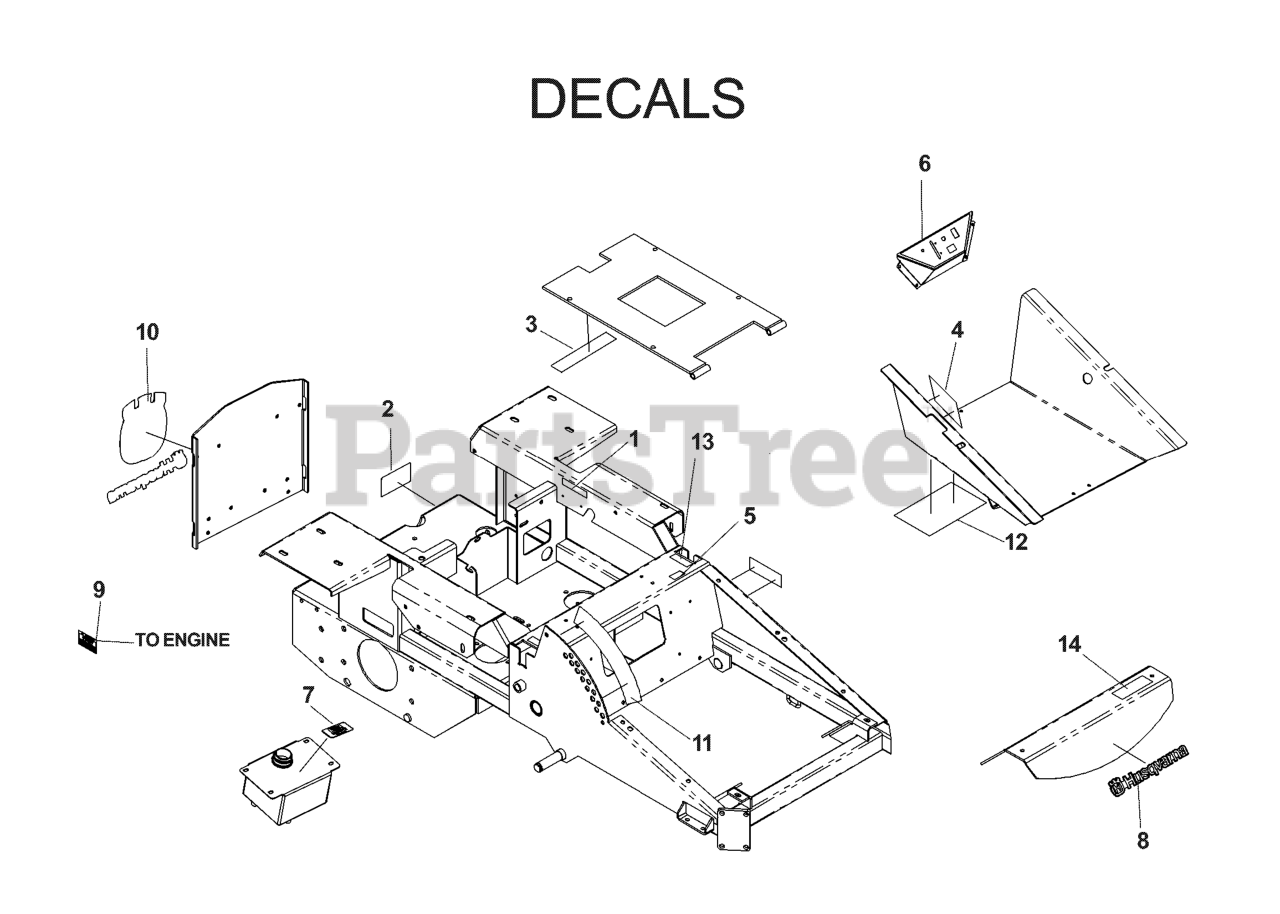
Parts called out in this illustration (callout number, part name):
1	DECAL, RELAYS
2	DECAL, BELT DRIVE
3	EURO DECAL-BATTERY WARNIN6
4	DECAL, WARNING
5	DECAL, F.S.T.
6	DECAL, CONSOLE
7	DECAL, OIL TANK
8	DECAL, HUSQ 12" BLUE
9	DECAL, EXHAUST
10	DECAL, CROWN H 5-1/4 SILVER
11	DECAL, HEIGHT, IZE
12	SERVICE DECAL
13	DECAL, MOTION CONTROL
14	DECAL, CE 968999306
